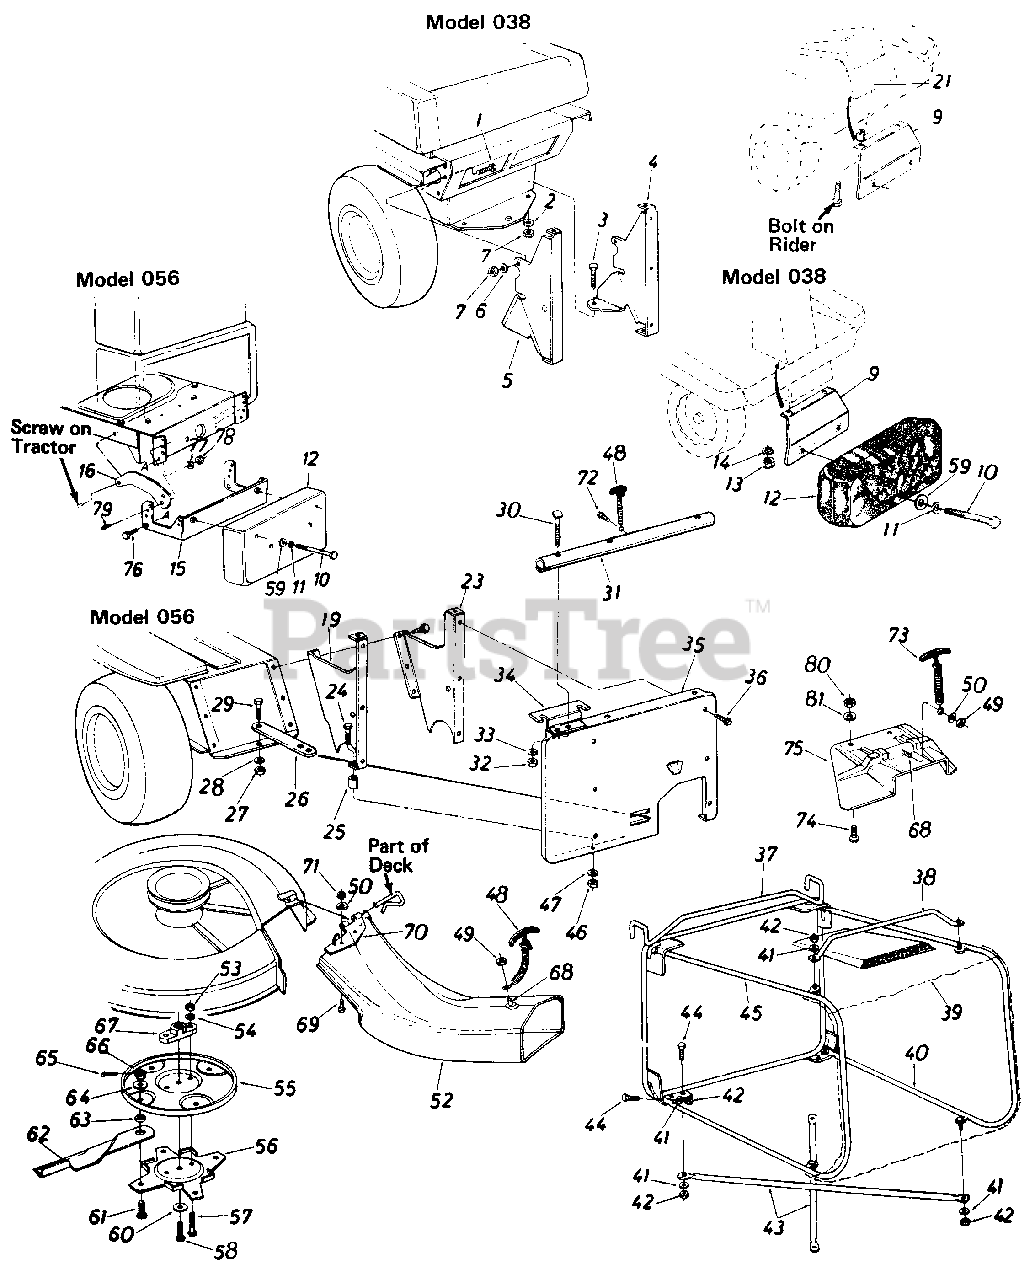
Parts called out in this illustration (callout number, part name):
1	Hex Bolt 5/16-18 x 1.0" Lg.*
2	L.-Wash. 5/16" I.D.*
3	Hex Bolt 5/16-18 x 1.0" Lg.*
4	Catcher Support Brkt - R.H.
5	Catcher Support Brkt - L.H.
6	L.-Wash. 5/16" I.D.
7	Hex Nut 5/16-18 Thd.*
9	Counterweight Support Brkt. Ass'y .
10	Hex Bolt 3/8-16 x 4.5" Lg.*
11	Belleville Wash. .40" I.D. x .88" 0. D.
12	Counterweight 38 lbs.
13	Hex Nut 5/16-18 Thd.*
14	L.-Wash. 5/16" I.D.*
15	Countervveight Support Brkt. Ass'y.
16	Tie Strap
19	Catcher Support Brkt.- L.H.
21	Spacer .380" I.D. x 1.0" O.D. x .32" Lg.
23	Catcher Support Brkt. - R.H.
24	Hex Bolt 5/16-18 x 1.50" Lg.*
25	Spacer .380" I.D. x .47" O.D. x 1.0" Lg.
28	L -Wash. 1/2" I.D.*
29	Hex Bolt 1/2-20 x 1.0" Lg.*
30	Curved Carriage Bolt 5/16-18 x 1.75" Lg.
33	L.-Wash. 5/16" I.D.*
34	Grass Catcher Support Plate
35	Rear Discharge Panel
36	Hex Wash. Hd. Self Tap. Scr. 1/4- 20 x . 50" Lg.
37	Grass Catcher Frame Ass'y.
42	Hex L.-Nut 1/2-20 Thd
43	Bottom Cross Brace
44	Hex Bolt 1/4-20 x .62" Lg.
47	L-Wash. 5/16" I.D.
48	Hook Latch Ass'y.
49	Hex L.-Nut 1/4-20 Thd.
50	L.-Wash. 1/4" I.D.*
52	R.D. Banana Chute Ass'y.
53	Hex Nut 5/16-24 Thd.*
54	L.-Wash. 5/16" I.D.*
55	Upper Blade Disc
58	Hex Bolt 3/8-24 x 1.0" Lg.
59	Fl.-Wash. .39" I.D. x 1.12" O.D.
60	Bell.-Wash. 39" I.D. x 1.38"
61	Shld. Bolt. .50" Dia. x .360 Spec.
62	30" Blade Tip
63	Spacer . 505" 1. D . x . 7 5" O.D. x 1.25" Lg.
64	Fl.-Wash. .50" I.D. x 1.25" O.D.
65	Cotter Pin 3/32" Dia. x 1.0" Lg.
66	HexSlottedNut1/2-20Thd.
67	Blade Adapter
68	Hex Bolt 1/4-20 x .50" Lg.*
69	Truss Mach. Scr. 1/4-20 x .50" Lg. *
72	Hex AB Tap Scr. 1/4 x .62" Lg.
73	Hook Latch Ass'y. 7" Lg.
74	Truss Mach. Scr. 1/4-20 x 50" Lg. *
75	R D Chute Extension
76	Hex Bolt 7/16-20 x 1.0" Lg.
77	L.-Wash. 7/16" I.D.*
78	Hex Nut 7/16-20 Thd.*
79	Self-Tap. Scr. 5/16-18 x 1.0" Lg.
80	Hex L.-Nut 1/4-20 Thd.
81	Fl.-Wash. .281" I.D. x .50" O.D. x .063
